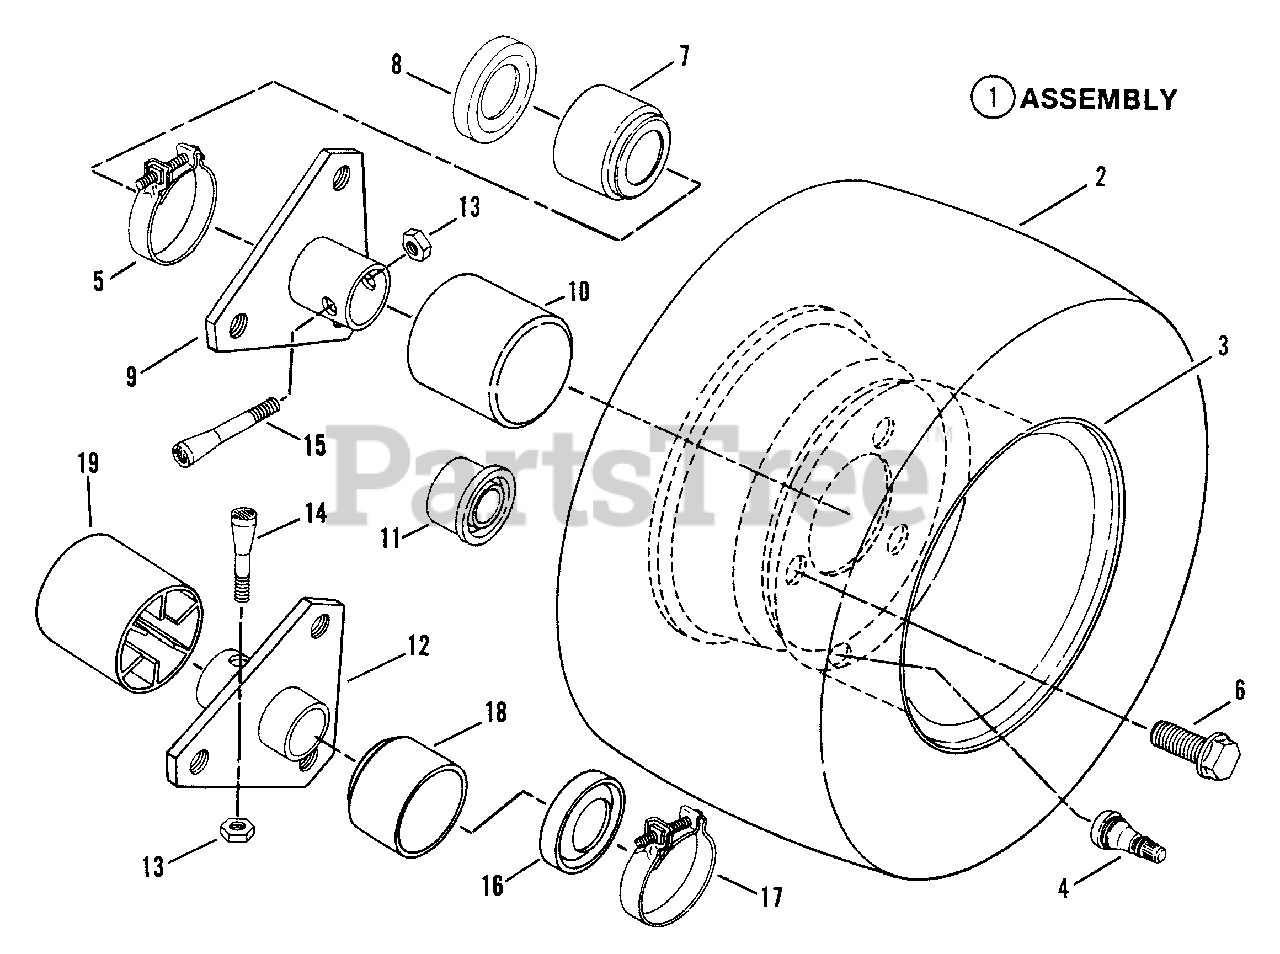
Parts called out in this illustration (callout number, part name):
1	ASSEMBLY, Rear Tire & Rim 16x4.80-8
1	ASSEMBLY, Rear Tire & Rim 16x6.50-8
1	ASSEMBLY, Rear Tire & Rim (NLA)
2	TIRE, Std., 16x4.80-8
2	TIRE, Wide, 16x6.50-8
2	TIRE, Ext Wide, 16x7.50-8
3	WHEEL/RIM, 4.80/4.06x8 (3 hole) Gray
3	WHEEL/RIM, 5.375x8 (3 hole) Gray
4	VALVE, Air (Snap-in)
5	CLAMP, 1 7/8" Right Hand
5	CLAMP, 2.69" Right Hand
6	BOLT, 1/2-20 x 3/4" Lug
7	CAP, Seal 1.0" ID x 1.67" OD Right Hand
7	CAP, Seal .93" ID x 2.625" OD Right Hand
8	SEAL, Oil 1.22" ID x 1.875" OD
9	HUB, Rear Wheel (Right Hand) 1.126" ID
10	CAP, Hub
11	CAP, Seal L.H. 3/4" ID
12	HUB, Rear Wheel .75" ID (Left Hand)
13	NUT, 5/16-24 Hex Center Lock
14	BOLT, 5/16-24 x 1-5/8" Tapered (Left Hand)
15	BOLT, 5/16-24 x 2" Tapered (Right Hand)
16	SEAL, Oil .750" ID x 1.832" OD (Left Hand)
17	CLAMP, (Left Hand)
18	BOOT, (Left Hand)
19	CAP, Hub (Left Hand)
